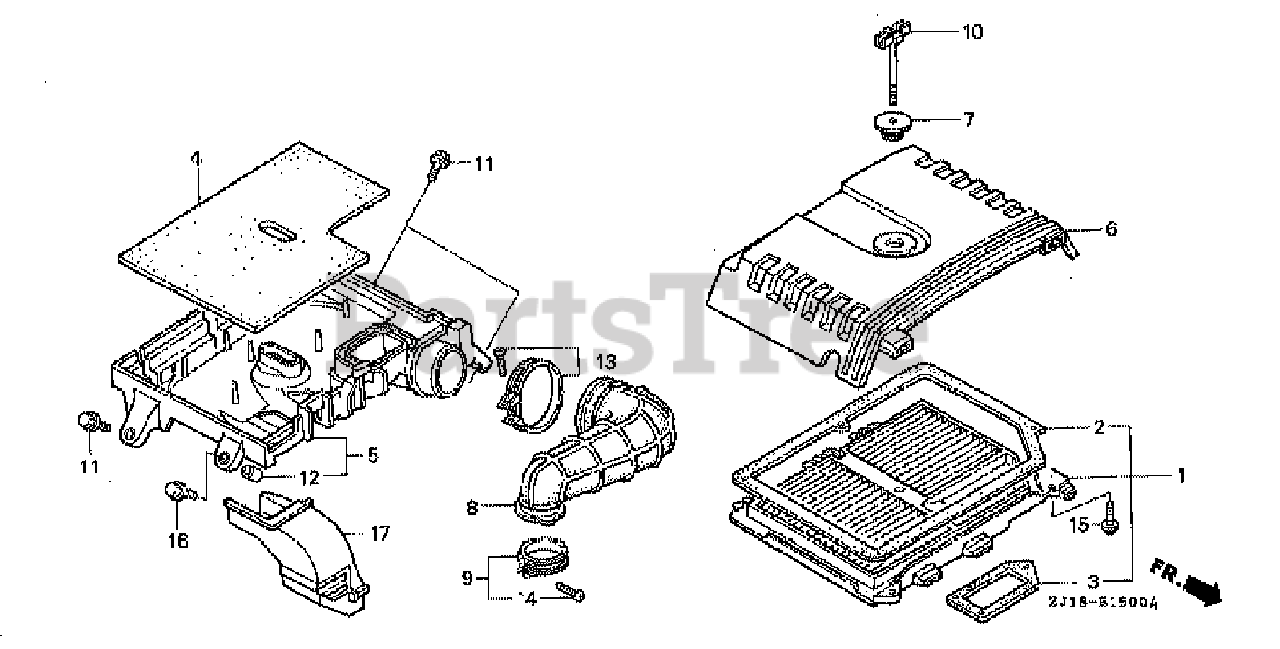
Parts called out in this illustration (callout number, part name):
1	ELEMENT SET, AIR CLEANER
2	GASKET A, ELEMENT
3	GASKET B, ELEMENT
4	FILTER (OUTER)
5	HOUSING, AIR CLEANER
6	COVER, AIR CLEANER
7	GROMMET, AIR CLEANER
8	TUBE, AIR CLEANER CONNECTING
9	BAND, AIR CLEANER CONNECTING TUBE
10	BOLT, AIR CLEANER
11	BOLT, FLANGE (6X23)
12	COLLAR, AIR CLEANER HOUSING
13	BAND, AIR CLEANER CONNECTING TUBE (50)
14	SCREW, PAN (4X20)
15	SCREW-WASHER (5X16)
16	BOLT, FLANGE (6X18)
